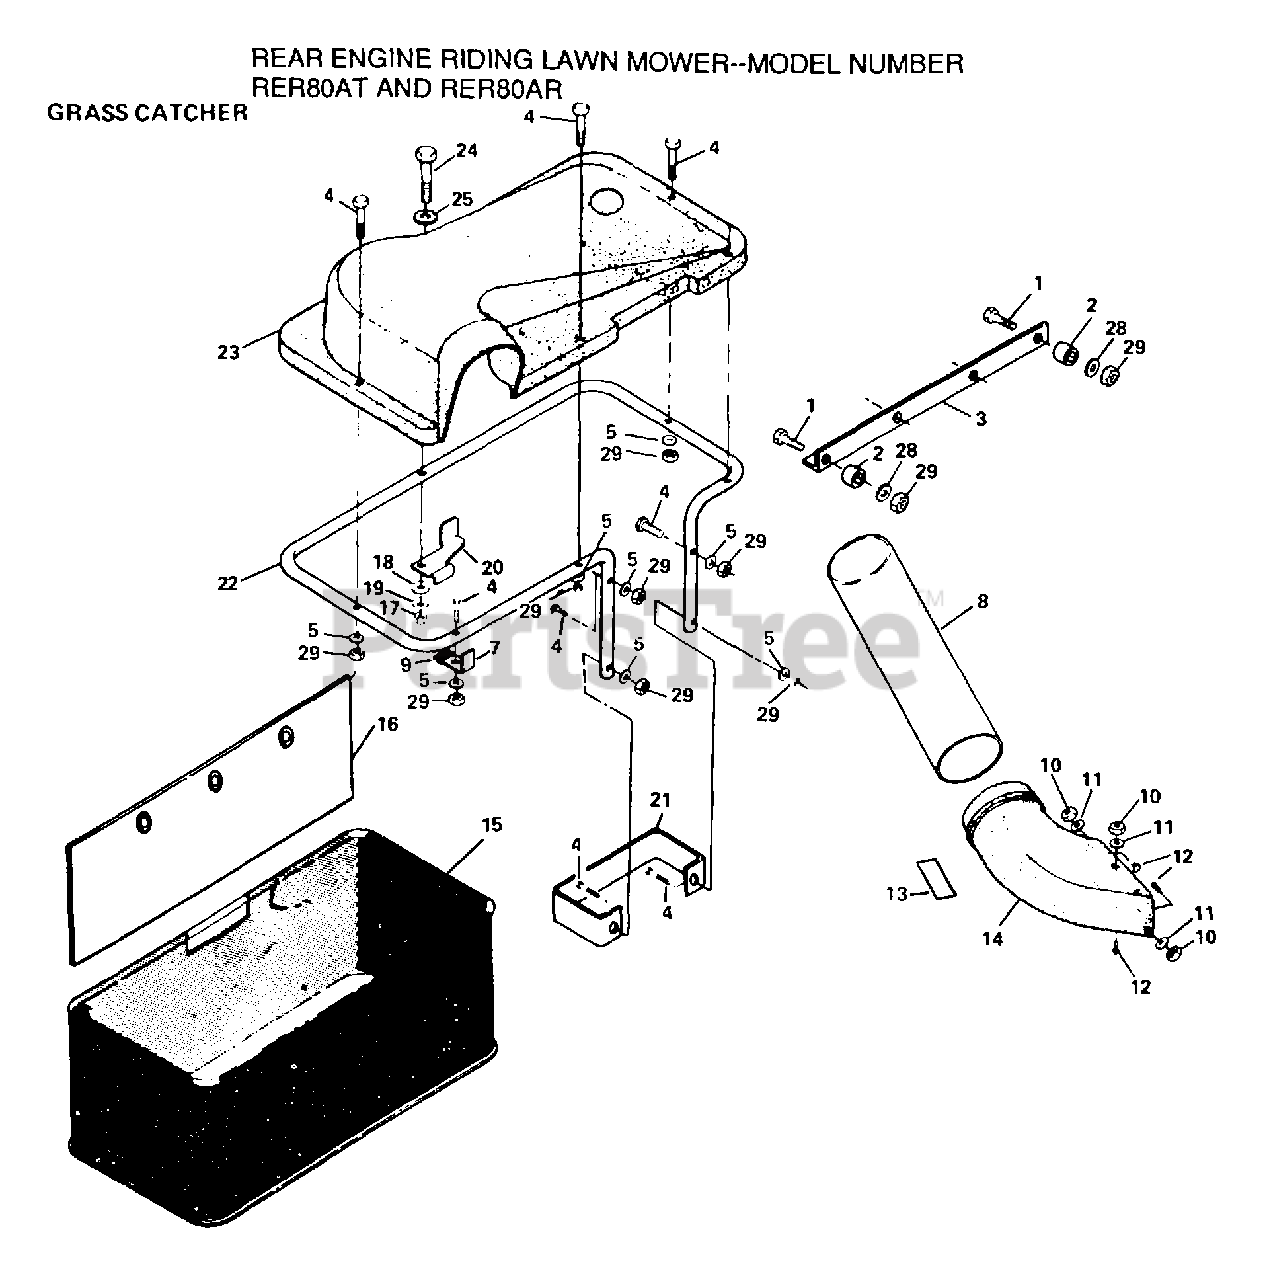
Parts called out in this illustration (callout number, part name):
2	SPACER T
4	BOLT
5	WASHER M
7	FRAME SUPPORT B
11	WASHER PM
18	LOCKWASHER
19	WASHER
25	WASHER
